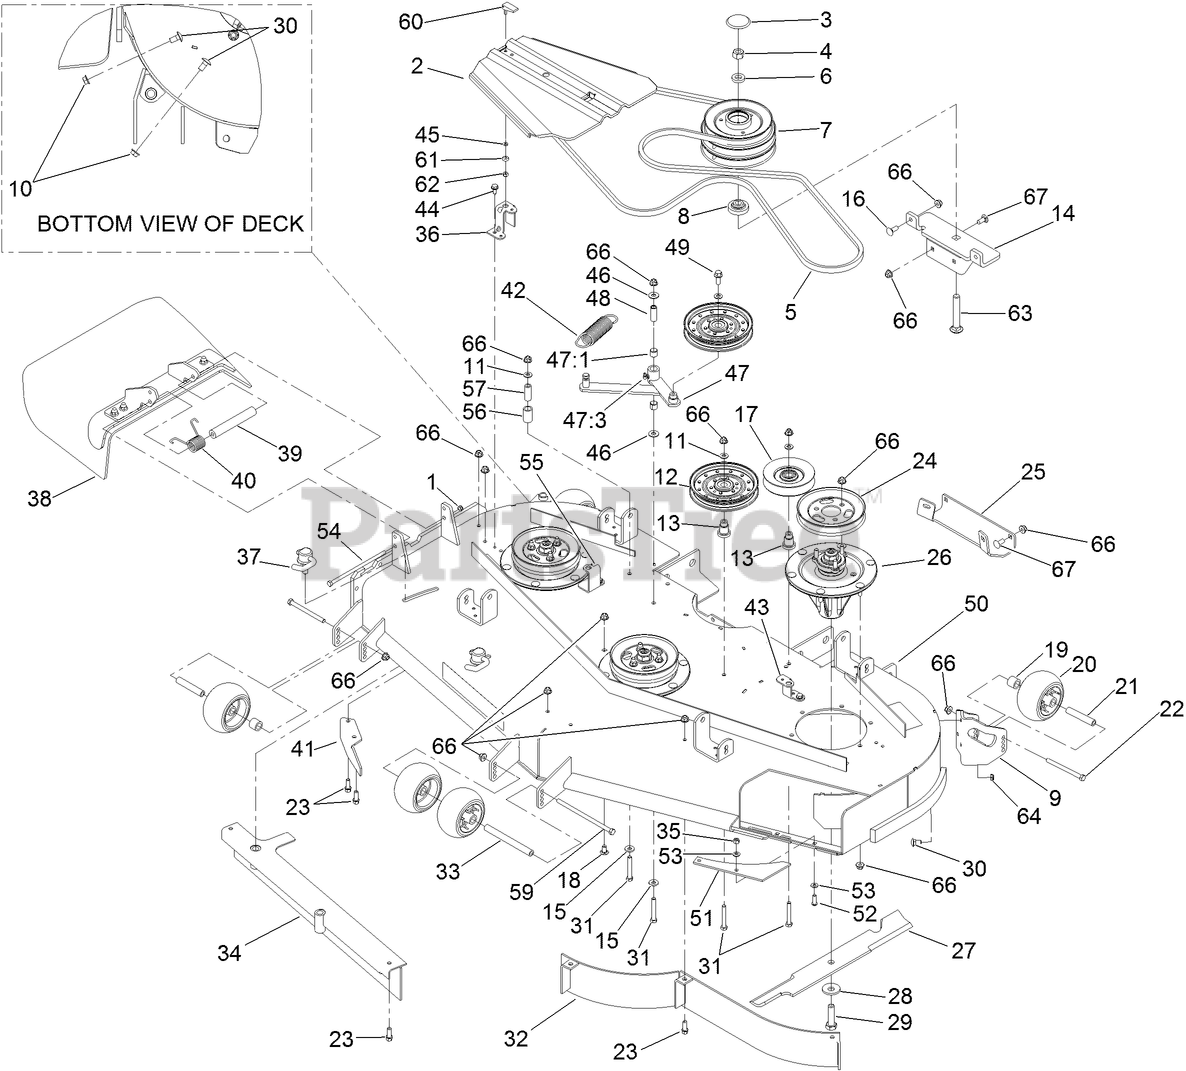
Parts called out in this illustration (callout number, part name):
1	NUT-LOCK, NI
2	COVER-BELT
3	CAP-PLASTIC
4	NUT-HEX
5	BELT-V
6	SPACER
7	PULLEY AND BEARING ASM
8	SPACER-FLANGED
9	MOUNT-WHEEL, LH
10	NUT-HHF, WHIZ
11	WASHER-FLAT
12	IDLER-PULLEY, FLAT
13	MOUNT-PULLEY
14	MOUNTING BRACKET ASM
15	WASHER-BELLEVILLE
16	BOLT-CARR
17	PULLEY-IDLER
18	SCREW-CARR
19	TUBE-SPACER
20	ROLLER-SCALP, ANTI
21	TUBE-SPANNER
22	SCREW-HH
23	SCREW-HWH
24	Pulley
25	Plate-Skid
26	SPINDLE ASM
27	BLADE-HI FLOW
28	Washer-Blade Bolt, Heavy
29	SCREW-BLADE
30	SCREW-CARR
31	SCREW-HH
33	SPACER-WHEEL
35	NUT-LOCK, NI
36	BRACKET-COVER
37	LEVER ASM
38	RUBBER DEFLECTOR ASM
39	SPACER
40	SPRING-TORSION
41	BAFFLE-DISCHARGE
42	SPRING-EXTENSION
43	BRACKET-COVER, TALL
44	SCREW-HWHTF
45	WASHER
46	WASHER-FLAT
47	IDLER ARM ASM
47:1	SLEEVE-BEARING
47:3	FITTING-GREASE, 90 DEG
48	BUSHING
49	SCREW-HHF
50	DECK DECAL ASM
51	PLATE-TURBO
52	SCREW-HSBH
53	WASHER-SPRING
54	SCREW-HH
55	BRACKET-COVER
56	SPACER-RUBBER
57	SPACER-PIVOT, IDLER
59	SCREW-HH
60	HANDLE-LATCH, SWELL
61	BUSHING-LATCH, SWELL
62	NUT-LOCK, HH
63	BOLT-CARRIAGE
64	NUT-LOCK, NI
66	NUT-HF, NI
67	SCREW-CARR
